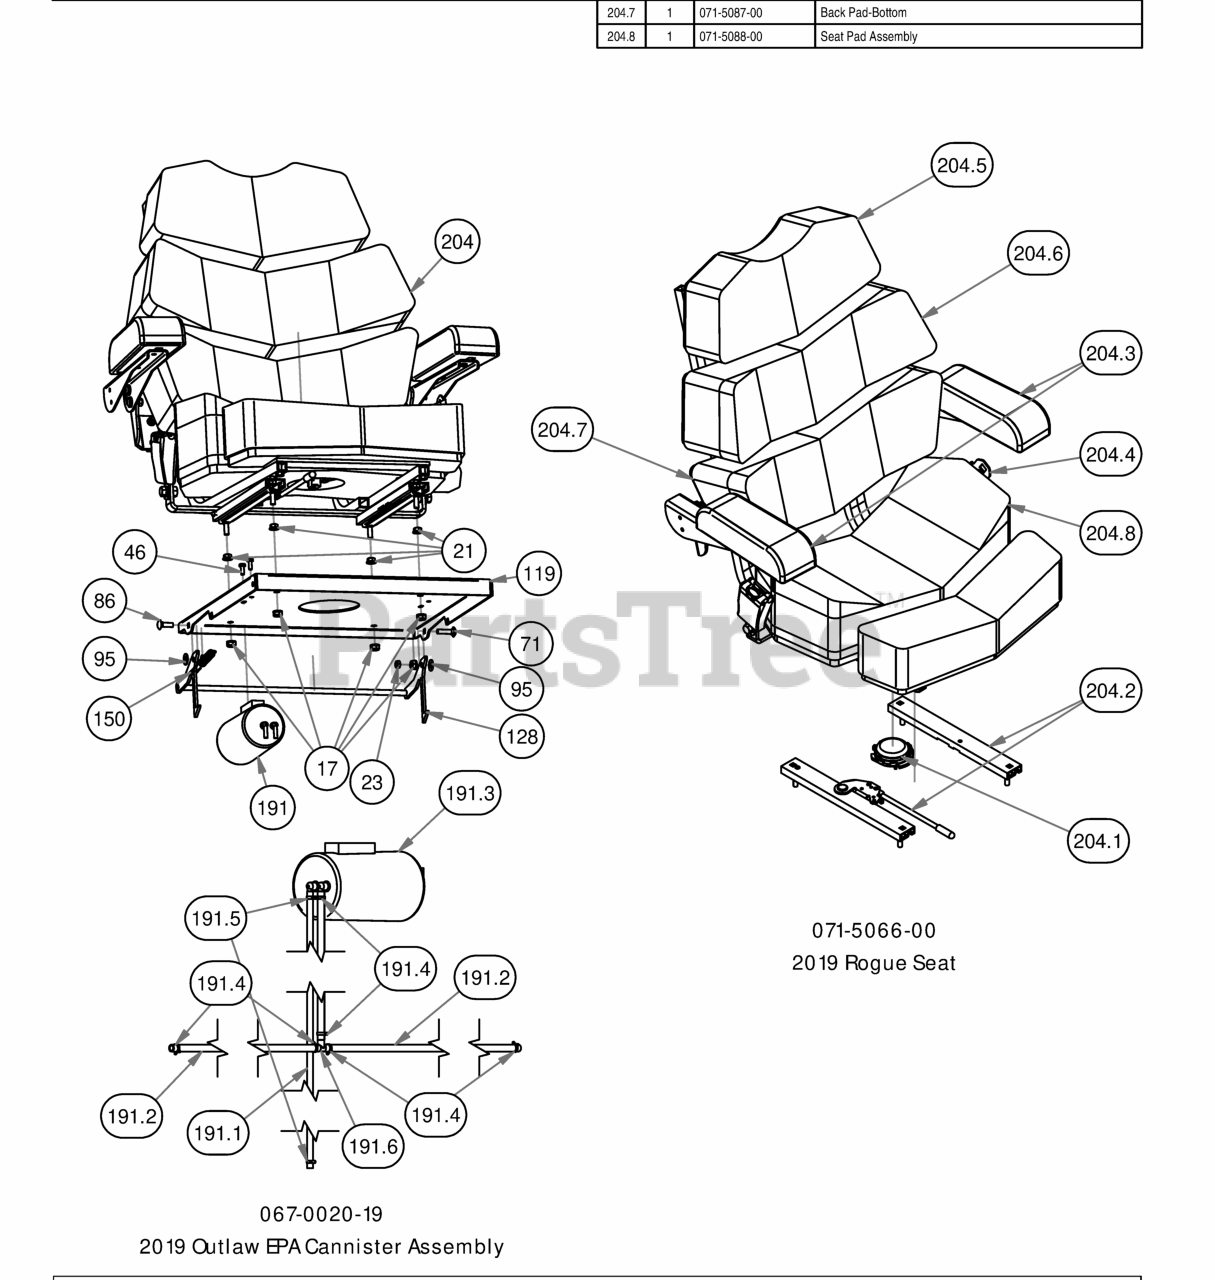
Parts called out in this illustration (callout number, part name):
17	5/16-18 Nylon Flange Nut
21	5/16" Flange Nut
23	5/16-18 Nylock Jam Nut 1/2 Nut
46	M6-1.0 X 16MM Hex Bolt
71	5/16" x 1 1/4" Carriage Bolt
86	5/16" x 1" Carriage Bolt
95	.360 ID Plastic Washer
119	2019 Outlaw Seat Plate
128	Seat Latch Rod Assembly
150	Brake Spring
191	2019 Outlaw EPA Cannister Assembly
191.1	3/16" Vinyl Tubing, 66" Long
191.2	1/4" Vinyl Tubing 38" Long
191.3	Carbon Canister
191.4	3/16 Vinyl Clamp
191.5	3/16" Vinyl Hose Clamp
191.6	fuel line T
204	2019 Rogue Seat
204.1	Seat Switch
204.2	Seat Rails
204.3	Arm Rest Kit
204.5	Back Pad-Top
204.6	Back Pad-Middle
204.7	Back Pad-Bottom
204.8	Seat Pad Assembly
